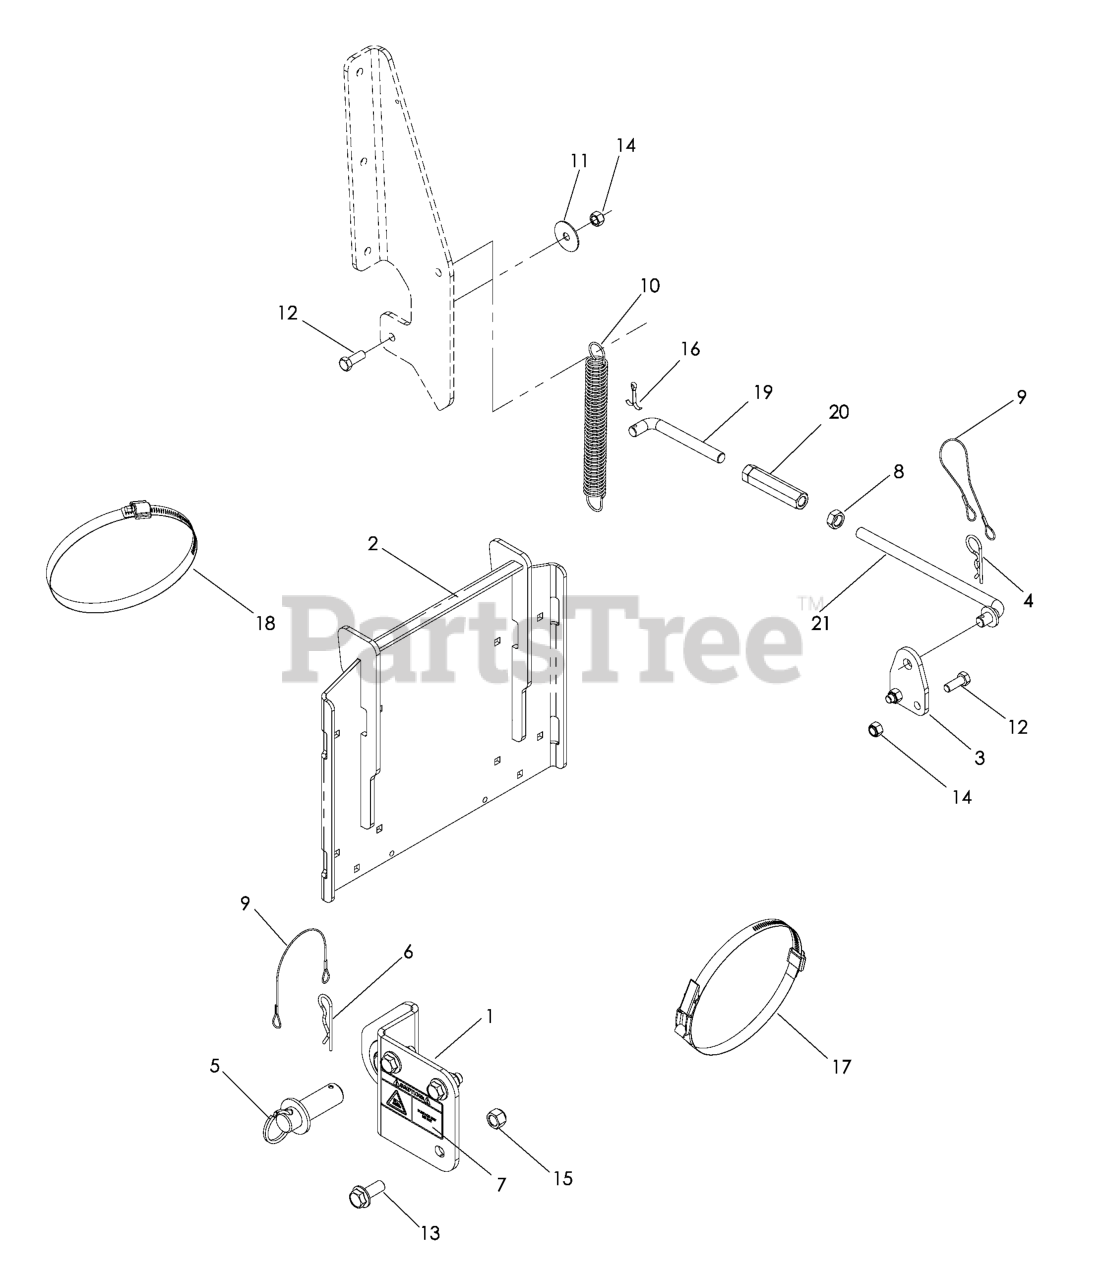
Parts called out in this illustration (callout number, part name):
1	HITCH BRACKET
2	HITCH BRACKET WLDMT
3	REAR GUARD WELDMENT
4	SUPPORT BRACKET
5	HAIRPIN #4
8	DECAL, HOT SURFACE
9	NUT 1/2-20 HEX JAM ZD
12	WASHER, FRICTION
13	HCS 3/8-16X1.GRD.5.ZD
14	HCS 1/2C X 1 1/4 SERRATED HEAD
15	NUT 3/8-16 NYLOC
16	NUT 1/2-13 HEX NYLOC ZD
17	COTTER PIN
18	OVER CTR BAND
19	HOSE CLAMP 4-1/8 TO 7"
20	SUPPORT LINKAGE, LH
21	TURNBUCKLE, 1/2
22	SUPPORT LINKAGE, LRG
